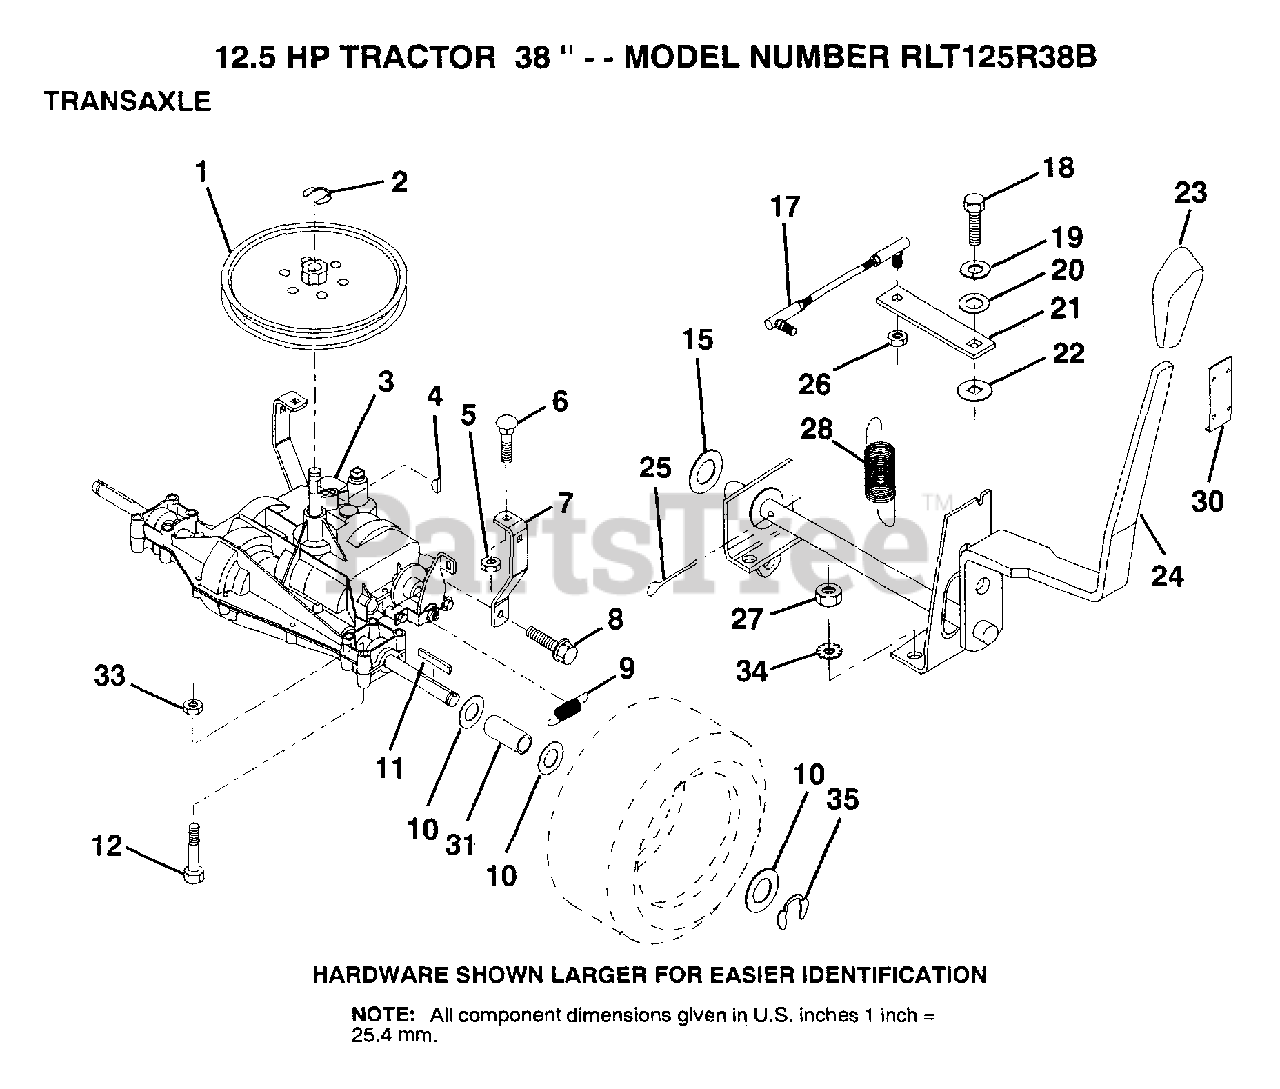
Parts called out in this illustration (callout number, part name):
1	PULLEY
3	TRANSAXLE.6SP.D
6	BOLT
7	"STRAP,TORQUE"
8	SCREW
10	WASHER
11	SQUARE KEY
12	BOLT
17	"LINK,SHIFT"
19	LOCKWASHER
20	WASHER LT
21	"ARM,SHIFT"
22	WASH-SHFT PLT LT
23	"KNOB,SHT CONTROL"
25	PIN COTTER 1/8
26	NUT.LOCK.5/16-24
28	"SPRING,EXT"
30	KNOB RETAINER
31	SPACER
34	LOCKWASHER.5/16.E
35	E-RING LT
